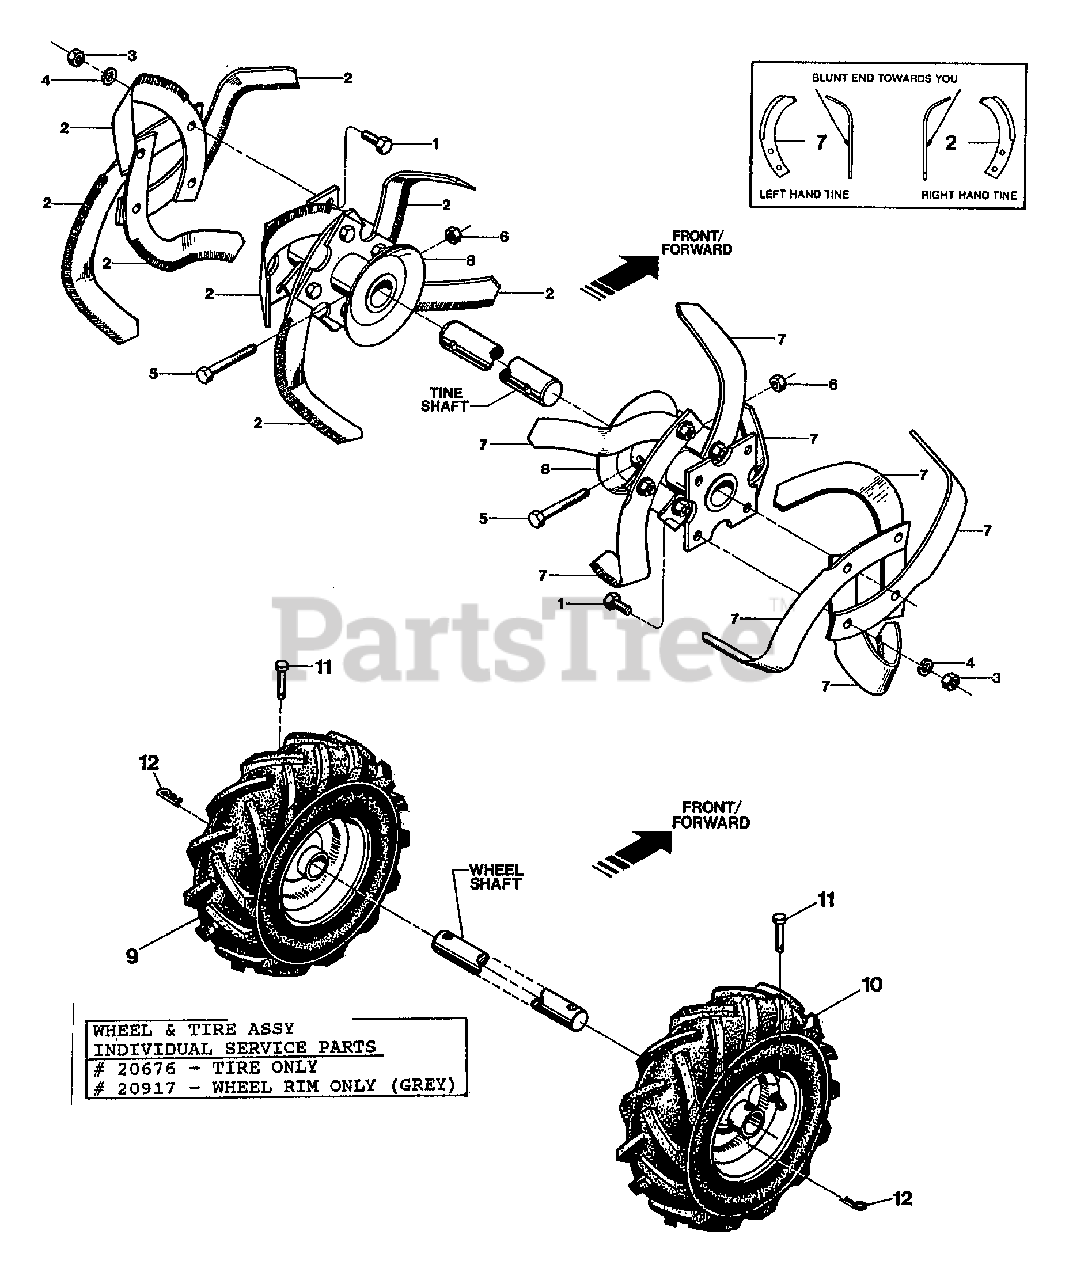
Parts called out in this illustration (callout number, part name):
1	SCR-HH 3/8-16X1.0 G5 ZP
2	TINE-BOLO RT W/HDW
3	NUT-HEX 3/8-16 ZP
4	WASHER-LK .375 @ DEPL
5	SCR-HH 3/8-16X2.00 G8
6	NUT-H/LK 3/8-16
7	TINE-BOLO LT W/HDW
8	WELD-TINE HOLDER PONY
9	ASSM-TIRE LT 4.10 X 6" (10-20 LBS. AIR REQ'D)
9	ASSM-TIRE RT 4.10 X 6" (10-20 LBS. AIR REQ'D)
9	RIM-WHEEL 6" GRAY
10	ASSM-TIRE RT 4.10 X 6"
11	PIN-CLEVIS .312"x1-3/4" LONG
12	PIN-CLIP .08
